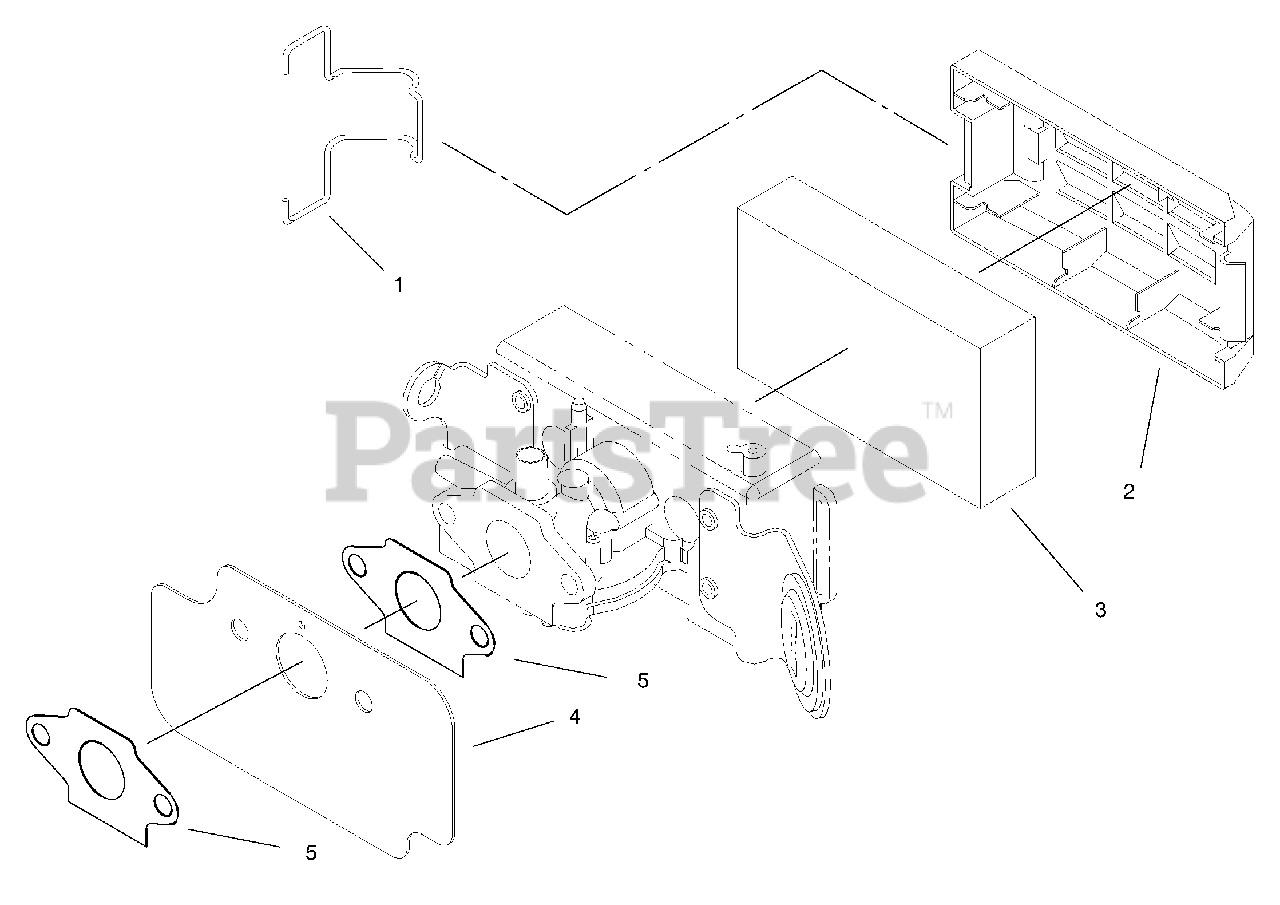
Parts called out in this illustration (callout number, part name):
1	Retainer-Cover
2	Cover-Air Filter
3	Element-Air Filter
4	Shield-Heat
5	Gasket-Carb.
